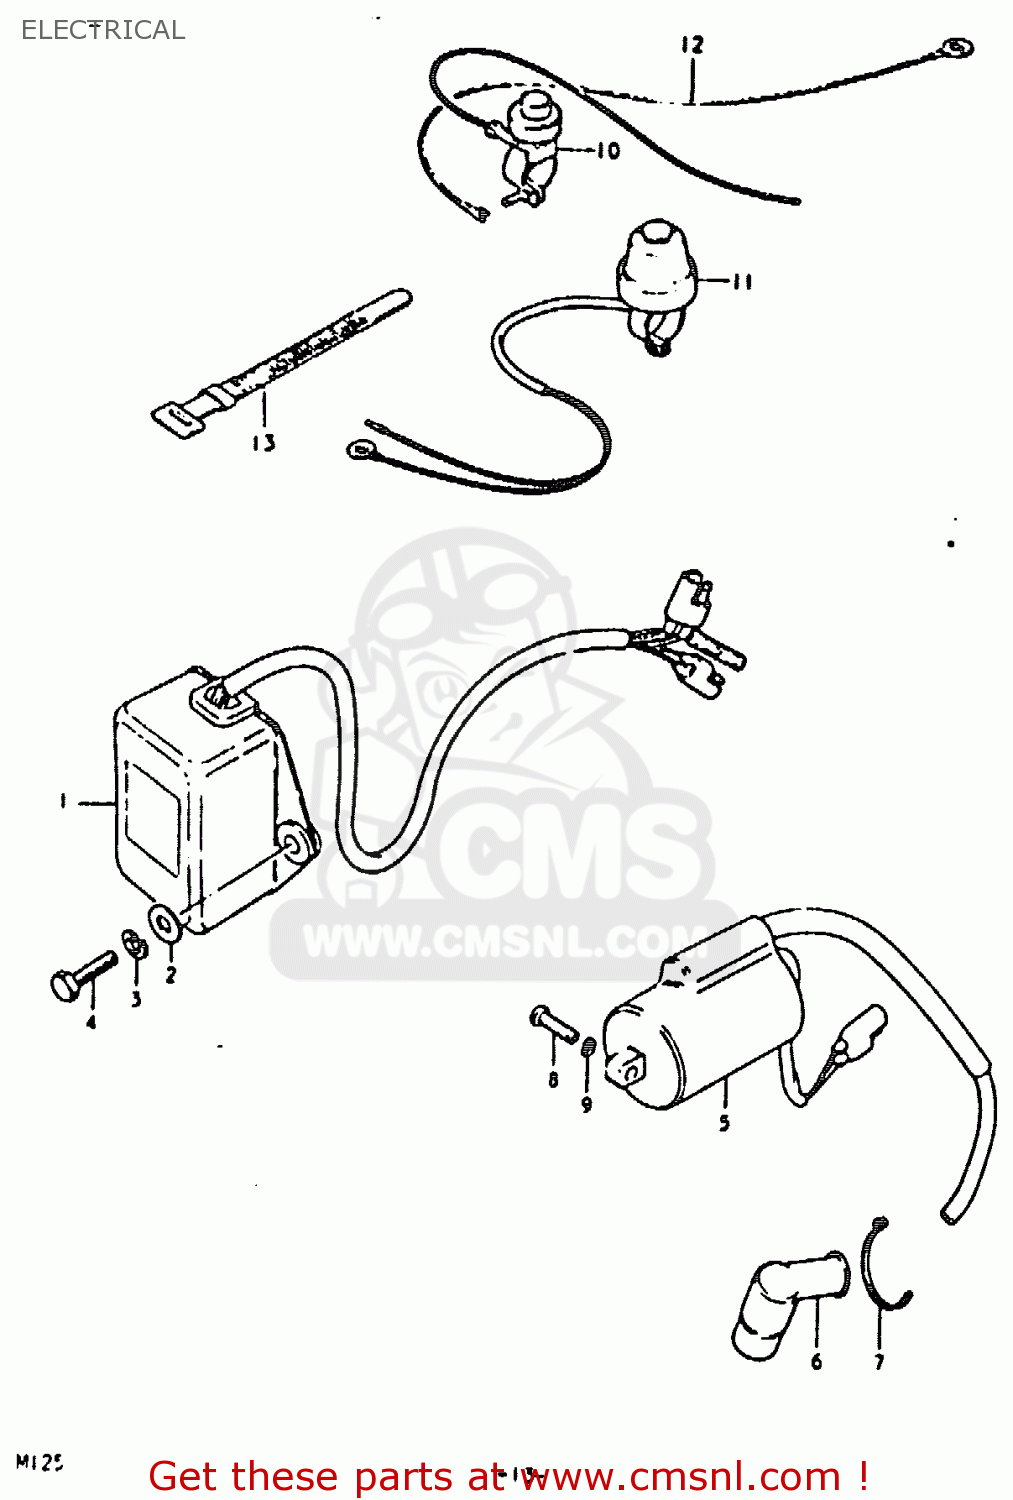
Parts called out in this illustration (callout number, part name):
1	CDI UNIT ASSEMBLY
2	WASHER(6.5X16X1.2)
3	LOCK WASHER
4	BOLT
5	COIL ASSEMBLY,IGNITION
6	CAP,SPARK PLUG
7	CLAMP
8	SCREW 5X20
9	LOCK WASHER
11	SWITCH ASSEMBLY
13	CLAMP(L:120)
